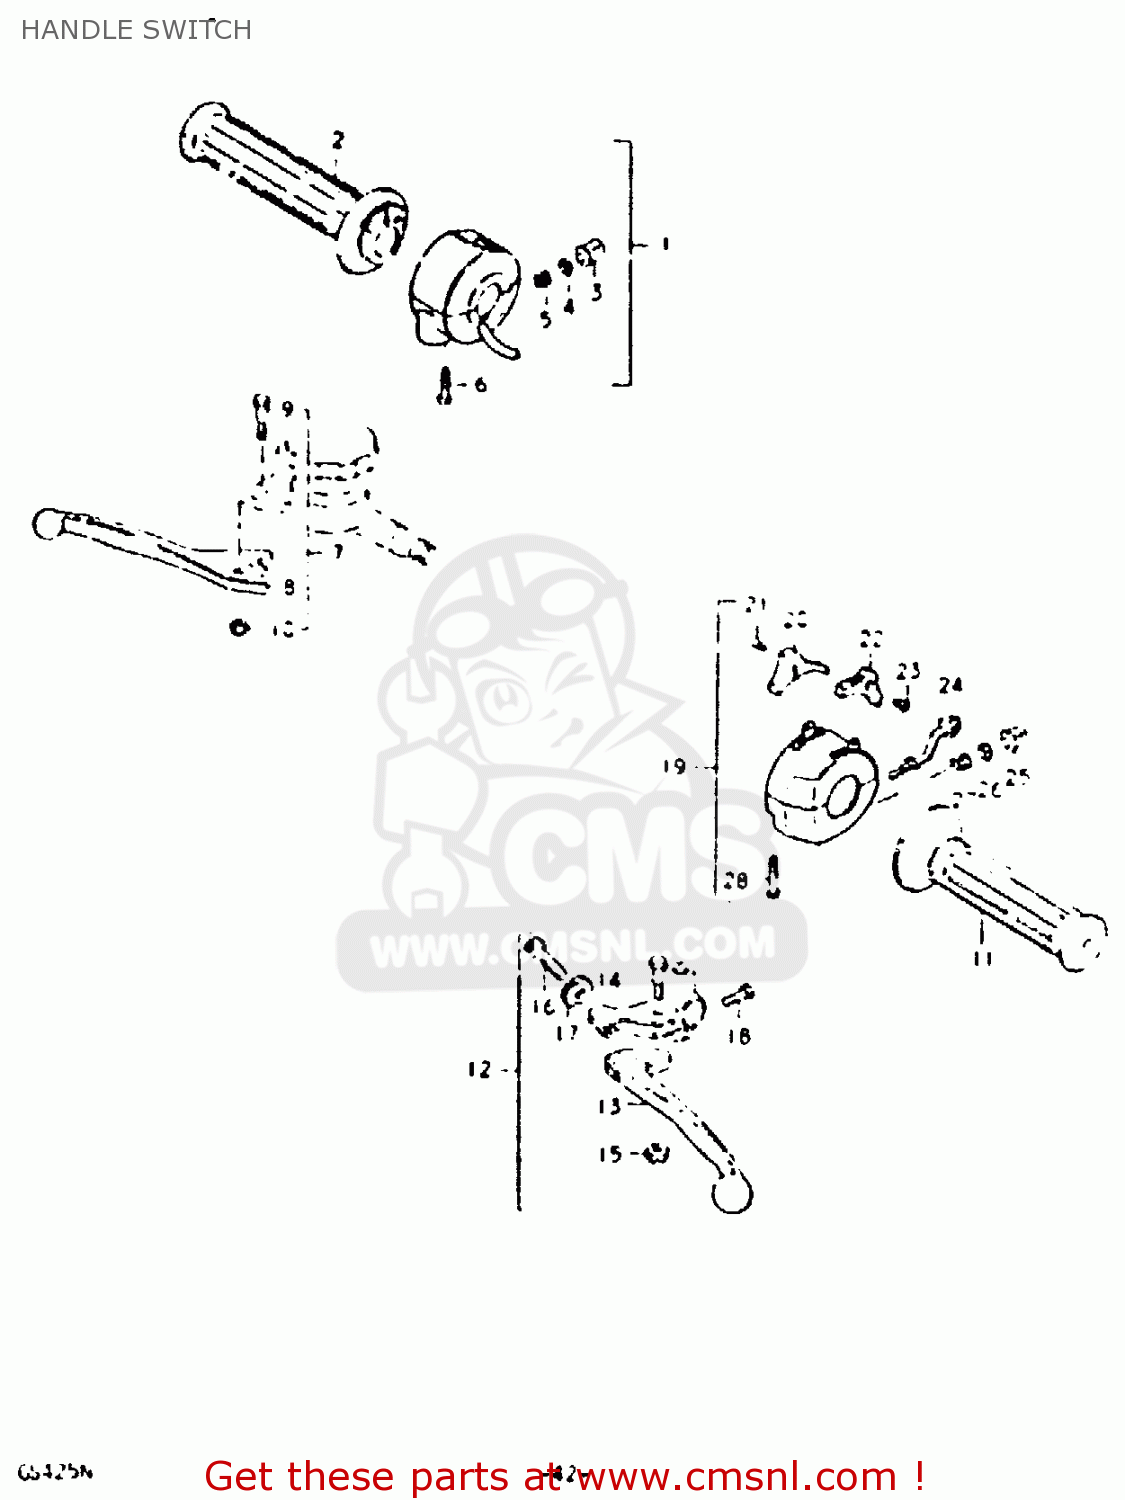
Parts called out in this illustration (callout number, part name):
1	CASE ASSEMBLY,THROTTLE
2	GRIP,THROTTLE
3	BUTTON,HORN
4	CONTACT
5	SPRING
6	SCREW
7	LEVER ASSEMBLY,BRAKE
8	LEVER,BRAKE
9	BOLT,LEVER
10	NUT 6MM
11	GRIP,LEFT
12	LEVER ASSEMBLY
13	LEVER,CLUTCH
14	BOLT,LEVER
15	NUT 6MM
16	ADJUSTER,CABLE
17	NUT,CABLE ADJUSTER
18	BOLT
19	SWITCH ASSY, HANDLE LH
20	KNOB,LIGHTING SWITCH
21	SCREW
22	KNOB,DIMMER SWITCH
23	SCREW
24	KNOB,TURNSIGNAL
25	BUTTON,HORN
26	CONTACT
27	SPRING
28	SCREW
